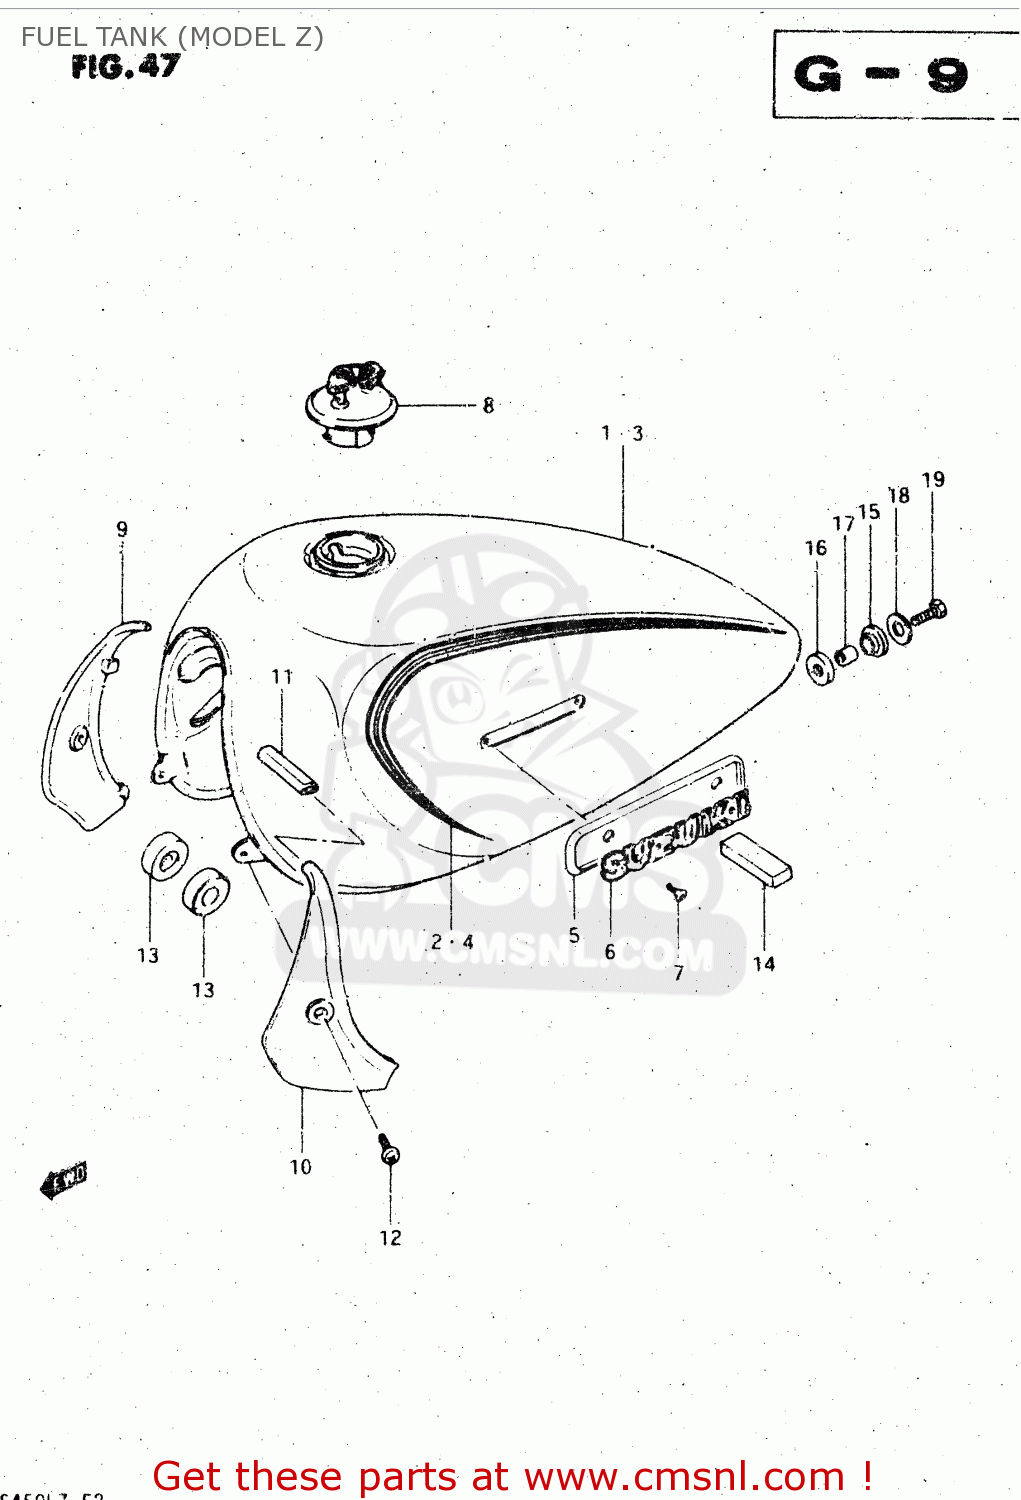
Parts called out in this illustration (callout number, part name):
1	TANK ASSEMBLY,FUEL
2	TAPE SET,FUEL TANK
3	TANK ASSEMBLY,FUEL
4	TAPE SET,FUEL TANK
5	CUSHION
6	EMBLEM,FUEL TANK
7	SCREW 3X6
8	CAP SET,FUEL TANK
9	COVER,FUEL TANK,FRONT,RIGHT
10	COVER,FUEL TANK,FRONT,LEFT
11	TUBE, FRONT
12	SCREW 6X12
13	CUSHION
14	CUSHION
15	CUSHION
16	CUSHION
17	SPACER(8.5X12X19)
18	WASHER (8.5X29X1.6)
19	BOLT (8X30)
